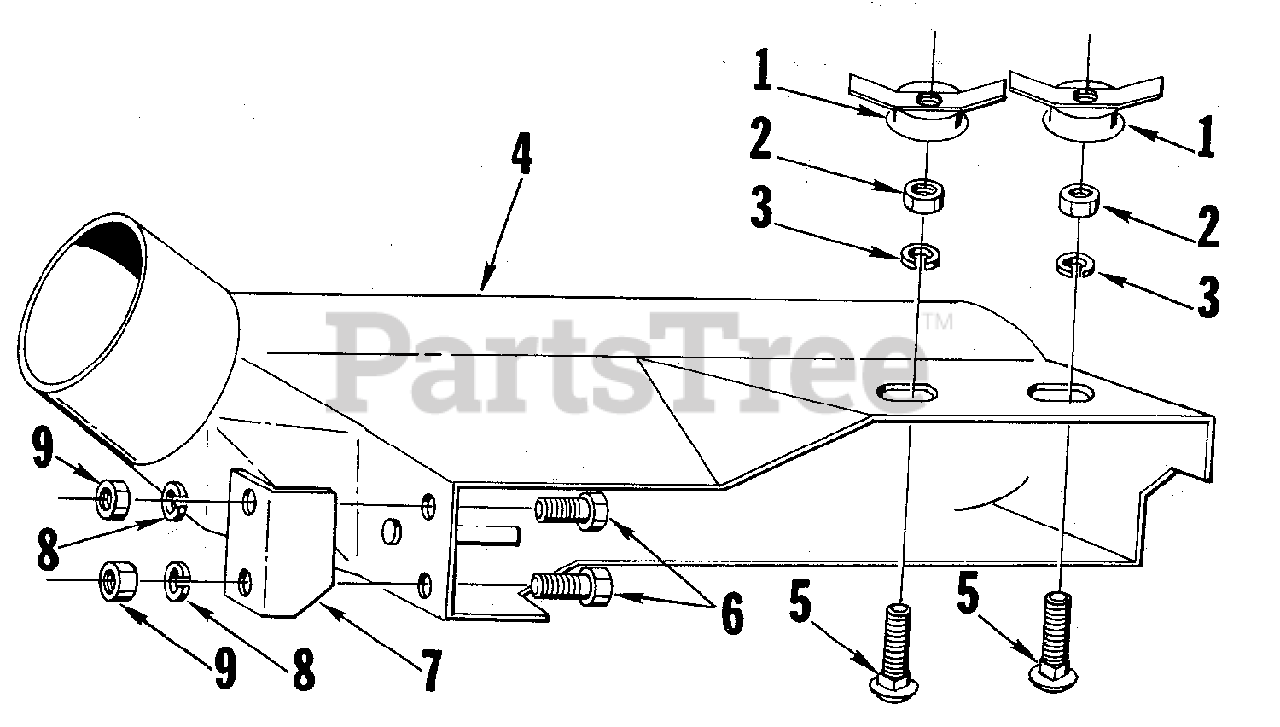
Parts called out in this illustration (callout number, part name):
1	NUT ASSEMBLY
2	NUT, Hex, 5/16-18
3	WASHER, Lock, 5/16"
4	ADAPTER ASSEMBLY, Vacuum Collector
5	BOLT, Carriage, 5/16-18 x 1
6	SCREW, Cap, 1/4-20 x 1/2
7	PIECE, Closure (32" Mower Only)
8	WASHER, Lock, 1/4
9	NUT, Hex, 1/4-20
